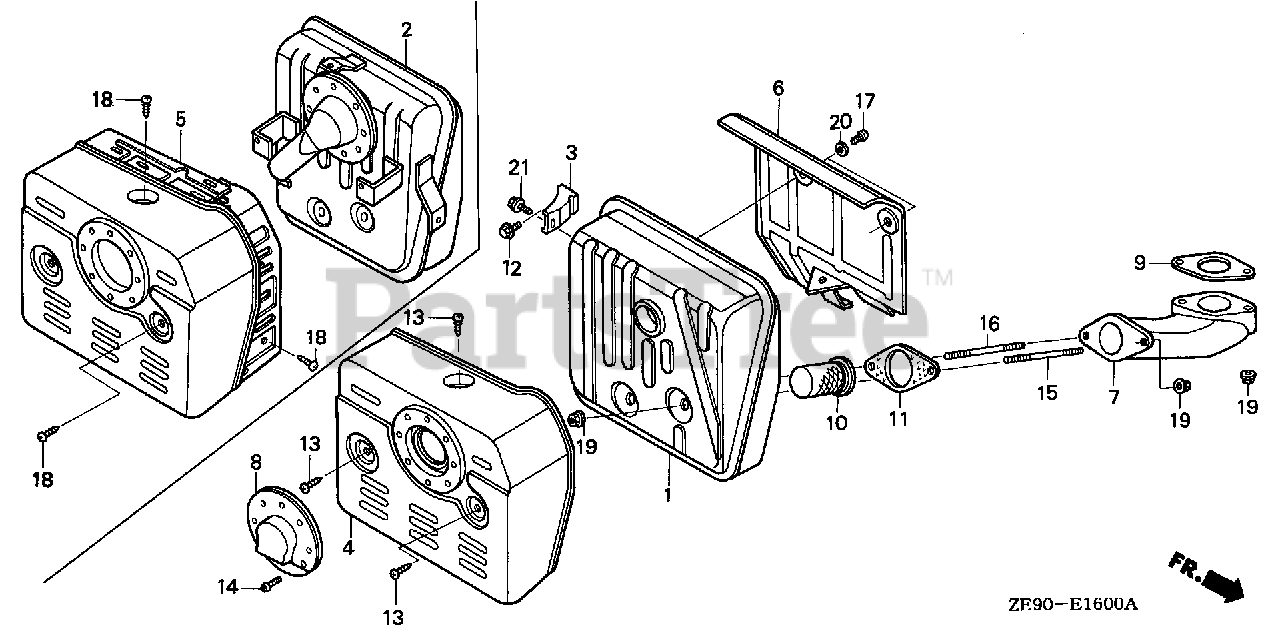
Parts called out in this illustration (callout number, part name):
1	MUFFLER
3	STAY, MUFFLER
4	PROTECTOR, MUFFLER
6	SEPARATOR, MUFFLER
7	PIPE, EX.
8	CAP, MUFFLER
9	GASKET, EX. PIPE
11	GASKET, EX. PIPE
12	BOLT, FLANGE (8X16)
13	SCREW, TAPPING (5X8)
14	SCREW, TAPPING (4X6)
15	BOLT, STUD (8X60)
16	BOLT, STUD (8X70)
17	SCREW, PAN (6X6)
19	NUT, FLANGE (8MM)
20	WASHER, PLAIN (6MM)
21	BOLT, FLANGE (8X14)
